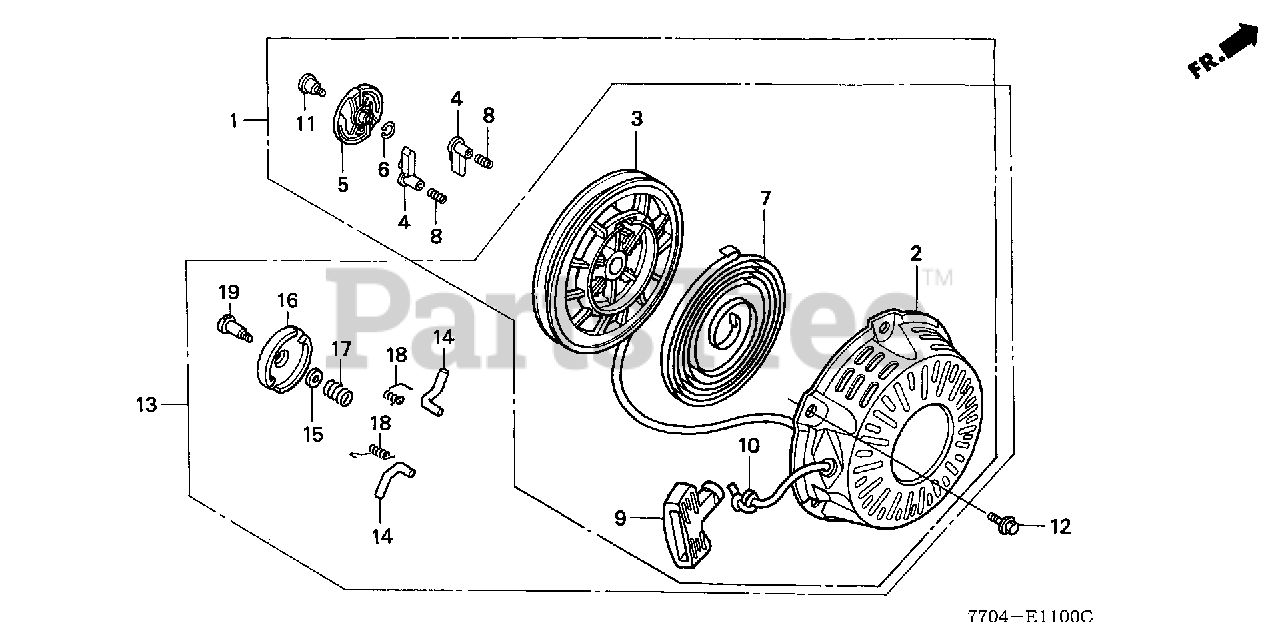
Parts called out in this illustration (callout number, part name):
2	CASE, RECOIL STARTER *R280* (POWER RED)
3	REEL, RECOIL STARTER (BLACK)
7	SPRING, RECOIL STARTER
9	GRIP, STARTER
9	KNOB, RECOIL STARTER
10	ROPE, RECOIL STARTER
12	BOLT, FLANGE (6X10)
13	STARTER ASSY., RECOIL *R280* (POWER RED)
14	RATCHET, STARTER
15	PLATE, FRICTION
16	GUIDE, RATCHET
17	SPRING, FRICTION
18	SPRING, RETURN
19	SCREW, SETTING
